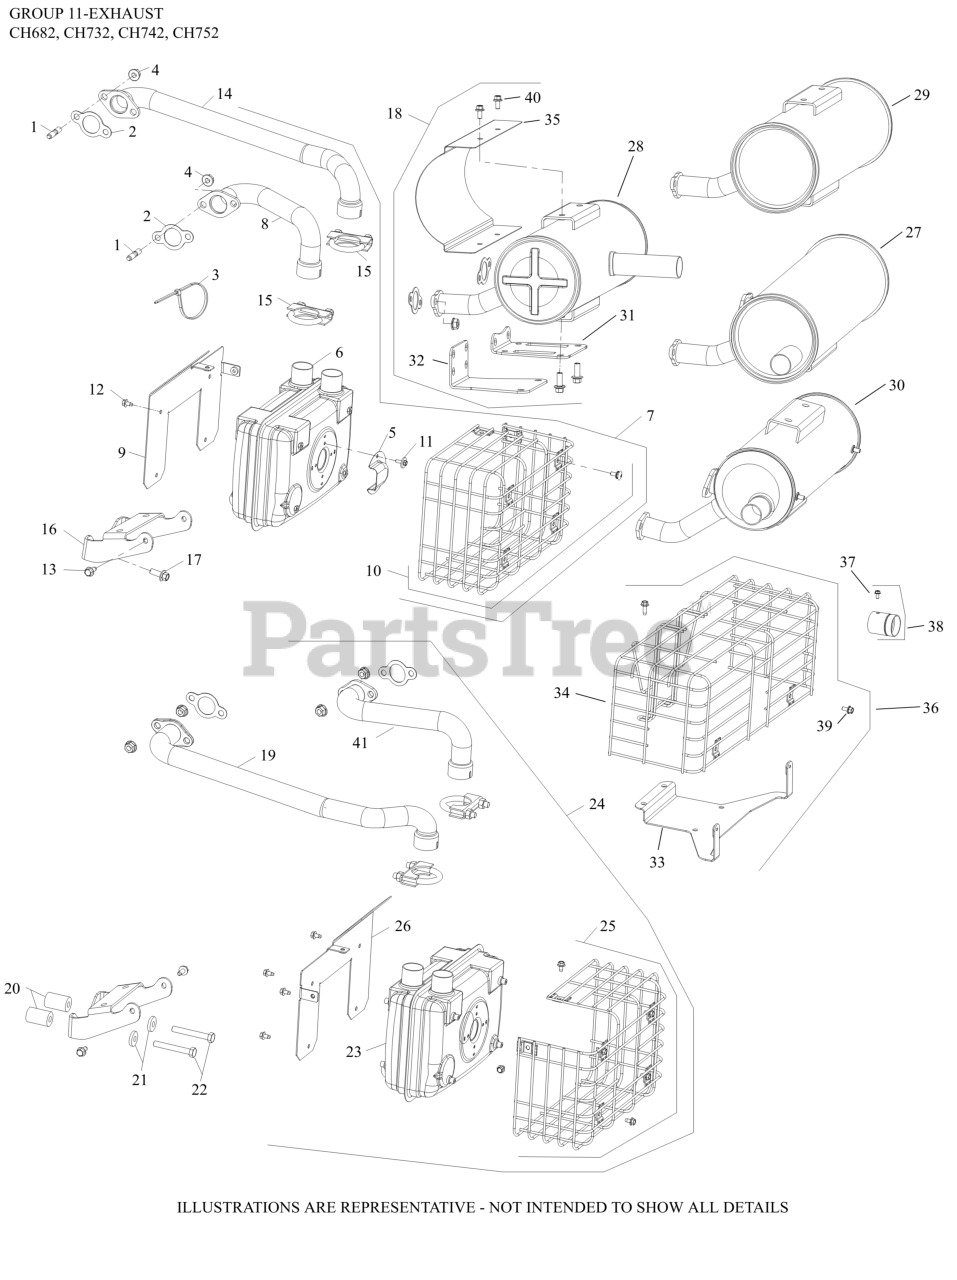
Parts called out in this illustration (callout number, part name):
2	GASKET, EXHAUST
4	NUT, FLG M8X1.25
18	KIT, MUFFLER
